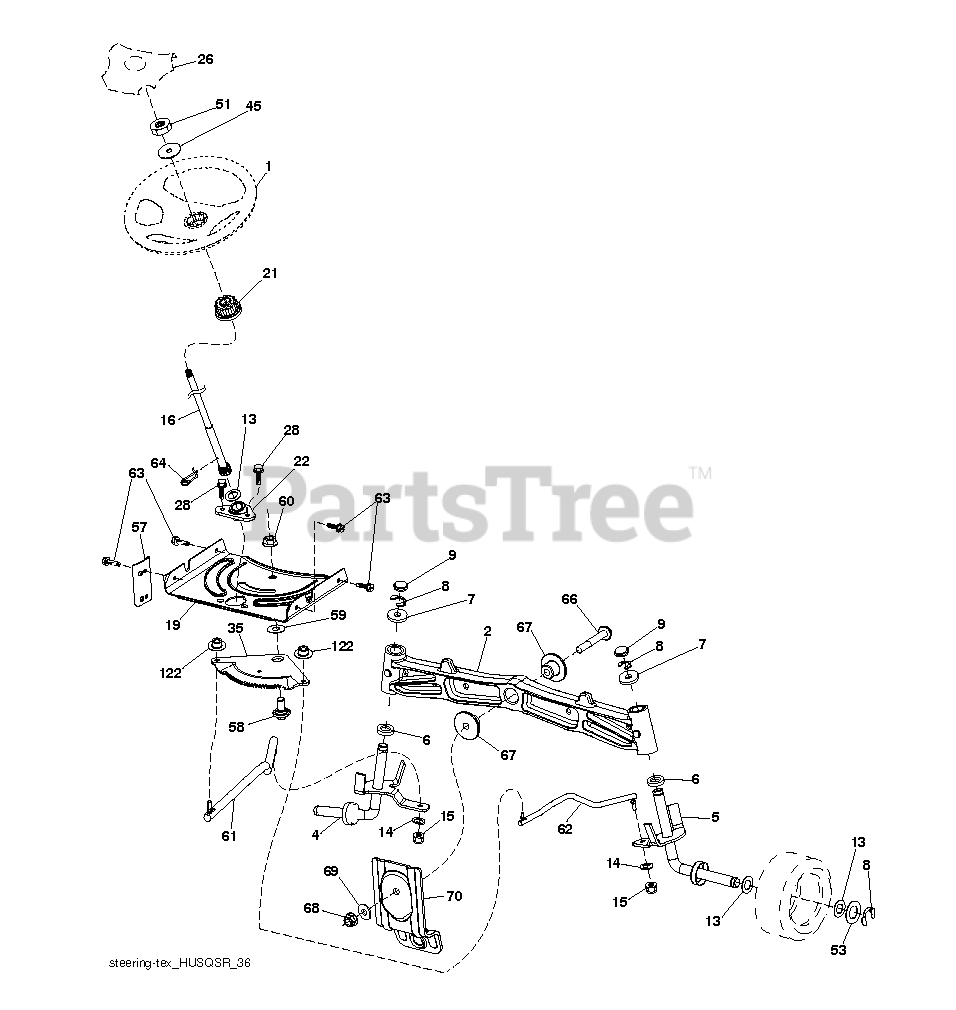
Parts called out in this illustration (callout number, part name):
1	WHEEL.STEER.HUSQ.SR.498.OVMLD
2	AXLE.CAST.IRON
4	SPINDLE.WELDED.LH.15"TEX
5	SPINDLE.WELDED.RH.15"T
6	THRUST WASHER
9	CAP.SPINDLE.BLACK
14	WASHER, LOCK 3/8
15	NUT CROWNLOCK 3/8-24
16	SHAFT, STEERING
19	PLATE.STEER.DDL.NLT/NG
21	ADAPTER, WHEEL STNG..
22	STEERING.SUPT.LOWER.
26	INSERT.CAP.WHL.STRG.HUSQ.PREM
28	SCREW, 3/8-16X3/4
35	GEAR.SECTOR.PLATE.DDL.
45	WASHER 9/16"ID, 2 3/8"OD
51	NUT.HEX.1/2-20
53	WASHER.HARDENED
57	BRKT.UPSTOP.GT/LT.TEX
58	BOLT.SHOULDER.SECTOR.P
59	WASHER.THURST.SECTOR.S
60	NUT FLANGE LOCK 5/8-11
61	DRAGLINK.LH.BALLSTUD.D
62	DRAGLINK.RH.BALLSTUD.D
63	SCREW
64	RETAINER.CLIP.SPRING.S
66	BOLT HEX FGHD 7/16-14 X 3 SERR
67	BUSHING.PM.FRONT AXLE
68	NUT.LOCK.FLANGE.7/16
69	WASHER.1.5X.505X.118
70	BRKT.DECK.SUSPENSION.F
122	CAP.GEAR.SECTOR.TEX
